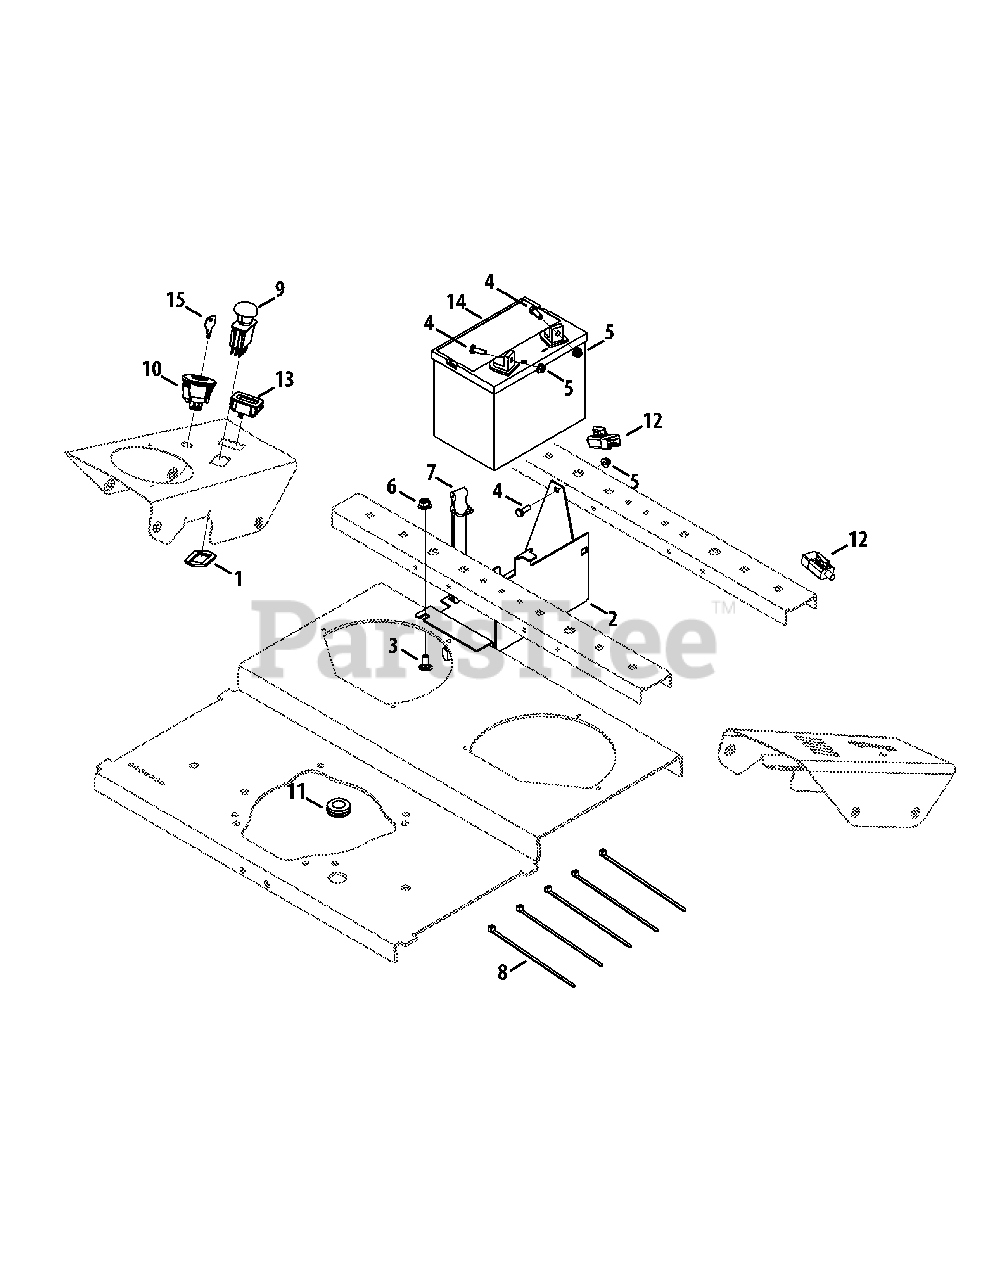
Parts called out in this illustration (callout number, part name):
1	PTO Switch Bracket
2	Battery Bracket
3	Carriage Bolt, 3/8-16 x .750
4	Hex Cap Screw, 1/4-20 x .75
5	Nut, 1/4-20, Flangelock
6	Nut, 3/8-16, Flangelock
7	Battery Strap
8	Cable Tie
9	Electric PTO Switch
10	Key Switch
11	Rubber Grommet, .75 x 1.062 x .50
12	Plunger Switch, NO/NC
13	Hour Meter
15	Key, Assembly
